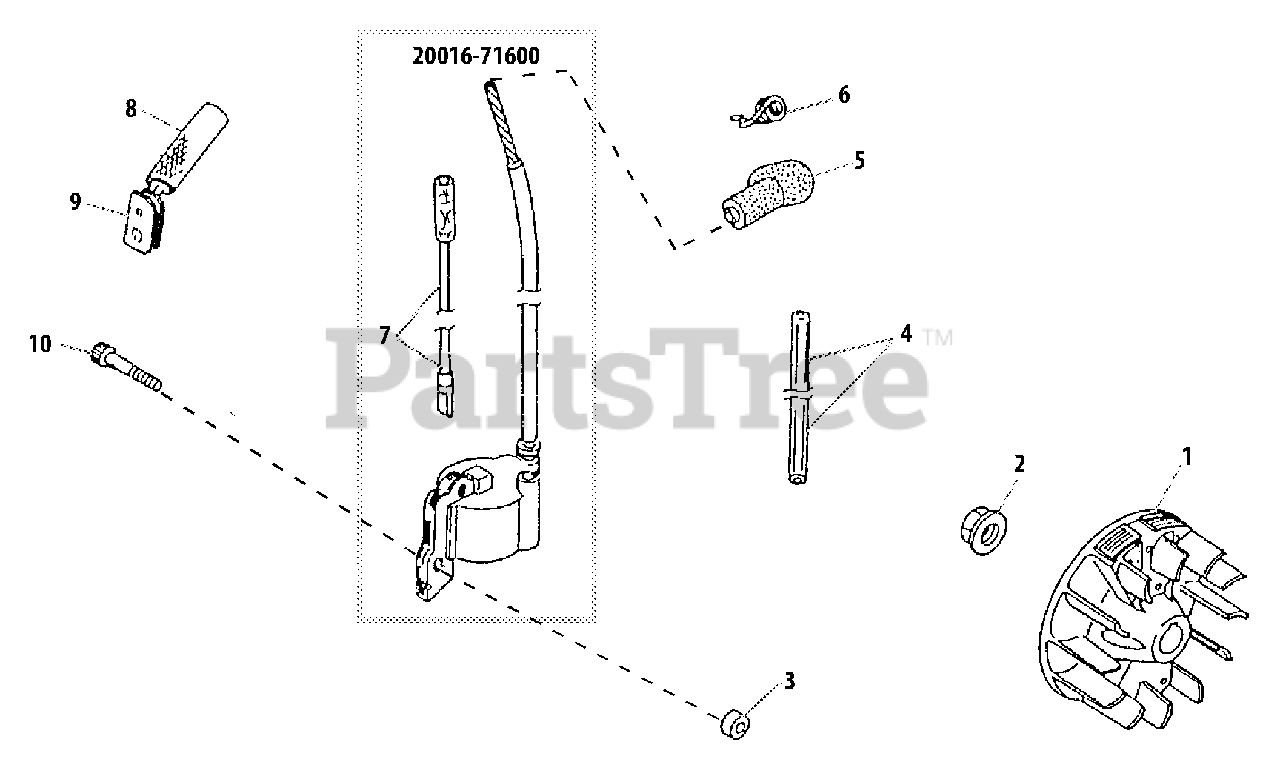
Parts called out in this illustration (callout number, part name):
1	FLYWHEEL
2	NUT - 8
3	INSULATOR
4	TUBE
5	CAP, SPARK PLUG
6	TERMINAL, SPARK PLUG CAP
7	LEAD - IGNITION
8	TUBE
9	GROMMET
10	SCREW - 4X26
20016-71600	IGNITION COIL ASSY
